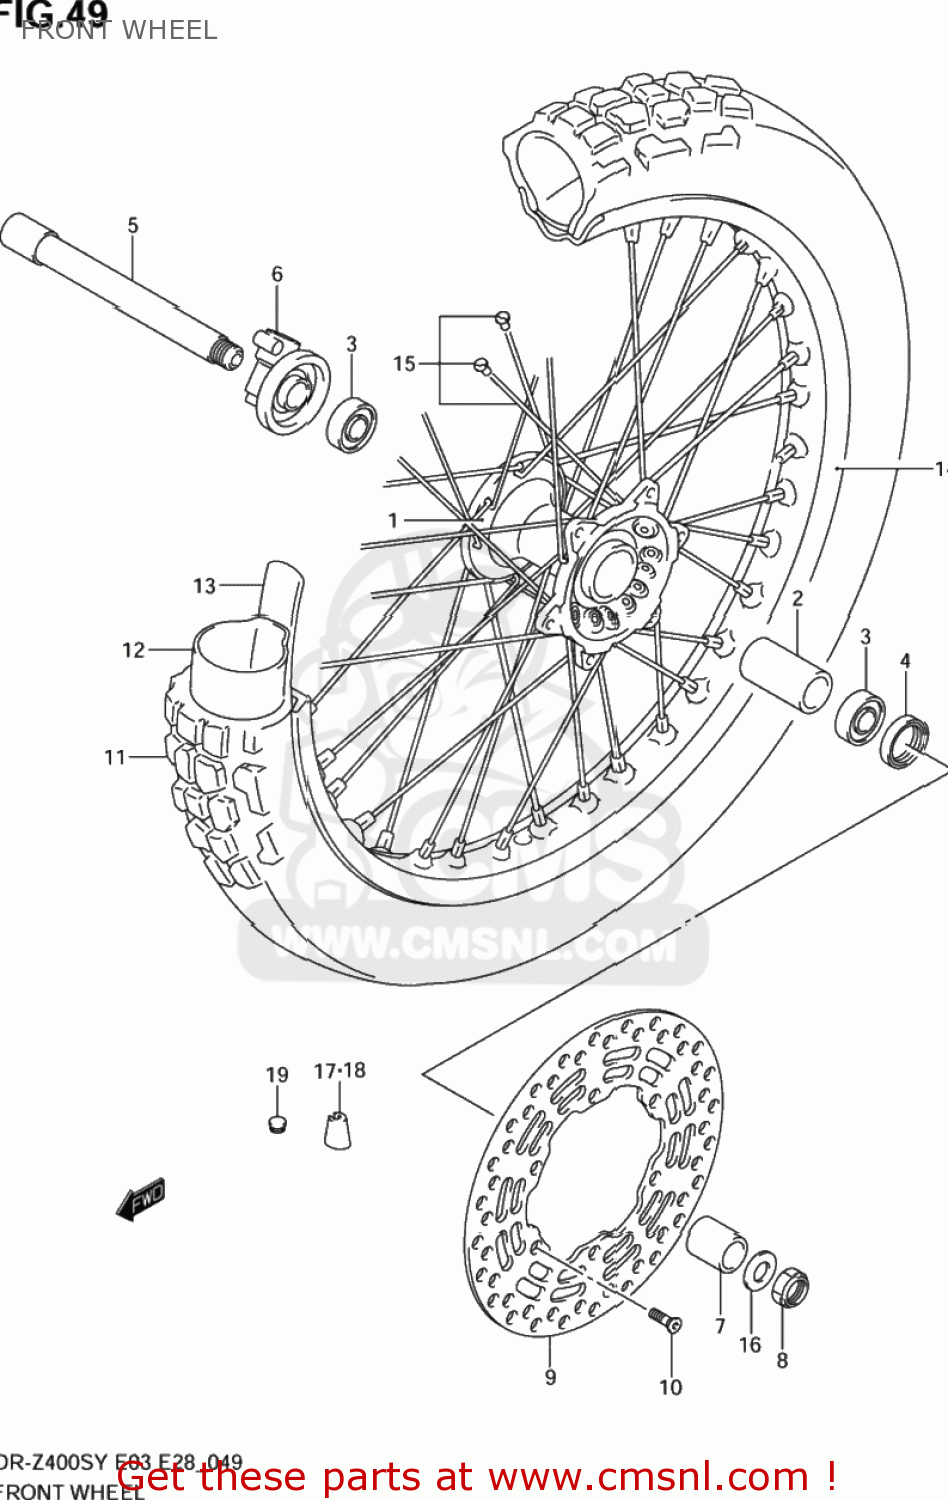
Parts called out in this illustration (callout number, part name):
1	HUB,FR WHEEL
2	SPACER,FR HUB BEARING
3	BEARING
4	SEAL,OIL(25X37X6)
5	AXLE,FR
6	BOX ASSY,SPEEDOMETER GEAR
7	SPACER,FR AXLE,L
8	NUT
9	DISC,FR BRAKE,L
10	SCREW
11	TIRE,FR(80/100-21 51P)
12	TUBE ASSEMBLY,WHEEL,INNER
13	PROTECTOR,WHEEL,INNER
14	RIM,FR WHEEL(21X1.60 AL)
15	SPOKE SET,FR WHEEL
16	WASHER(18X26X2.8)
17	BALANCER,WHEEL
18	BALANCER,WHEEL (30G)
19	CAP(OD:12)
